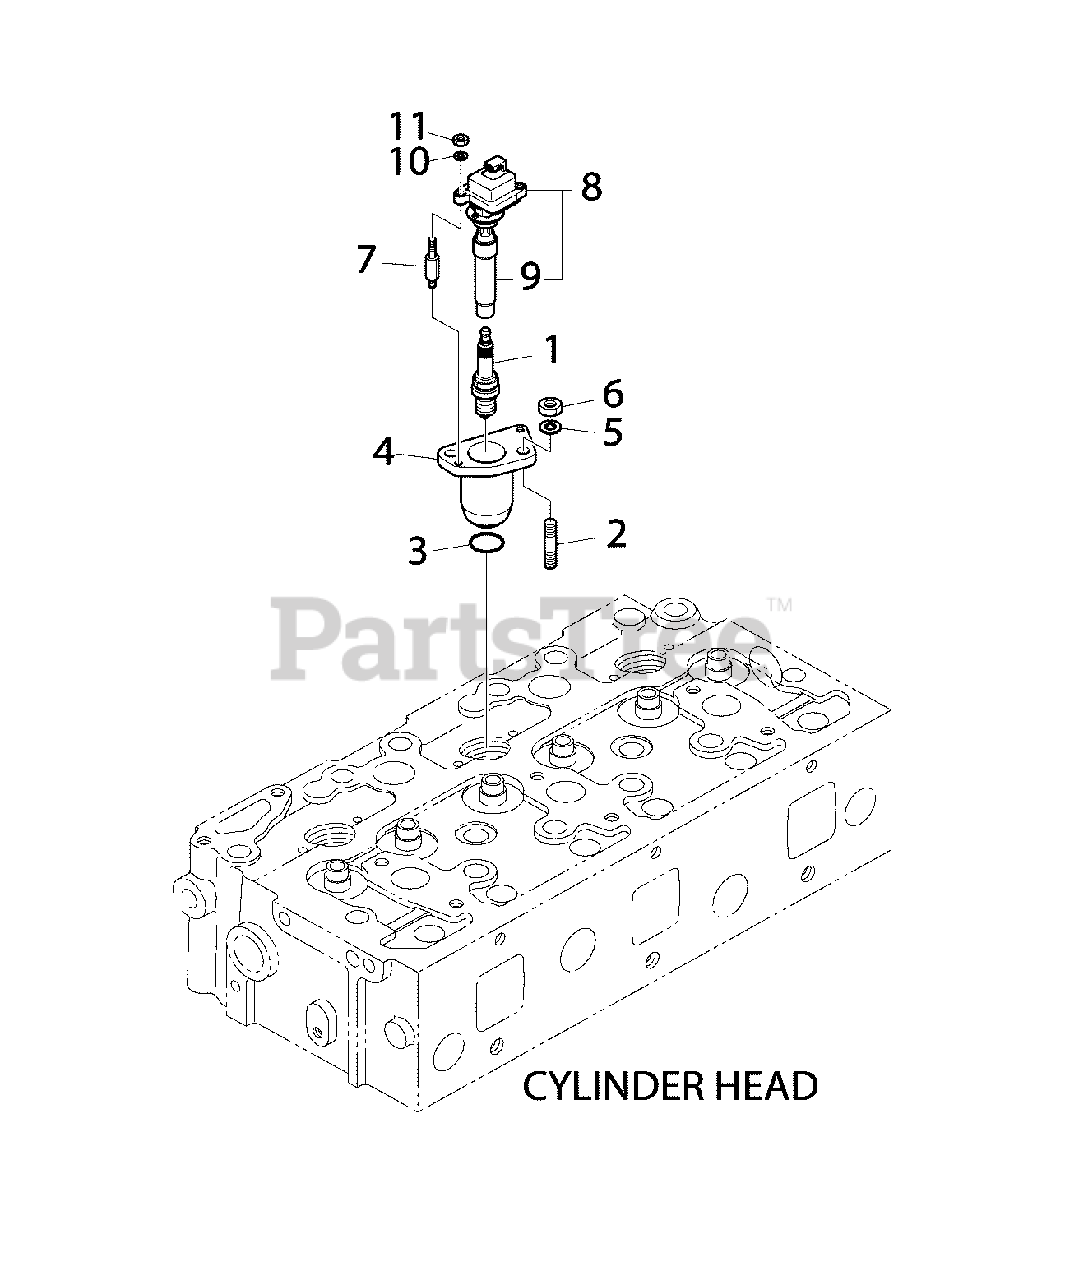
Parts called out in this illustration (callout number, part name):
1	PLUG, SPARK
2	* BOLT, STUD
3	GASKET
4	* COVER
5	* WASHER, SPRING
6	* NUT, HEX
7	* SPACER BOLT
8	COIL, IGNITION
9	BOOT, IGNITION COIL
10	* SPRING WASHER
11	* NUT, HEX
